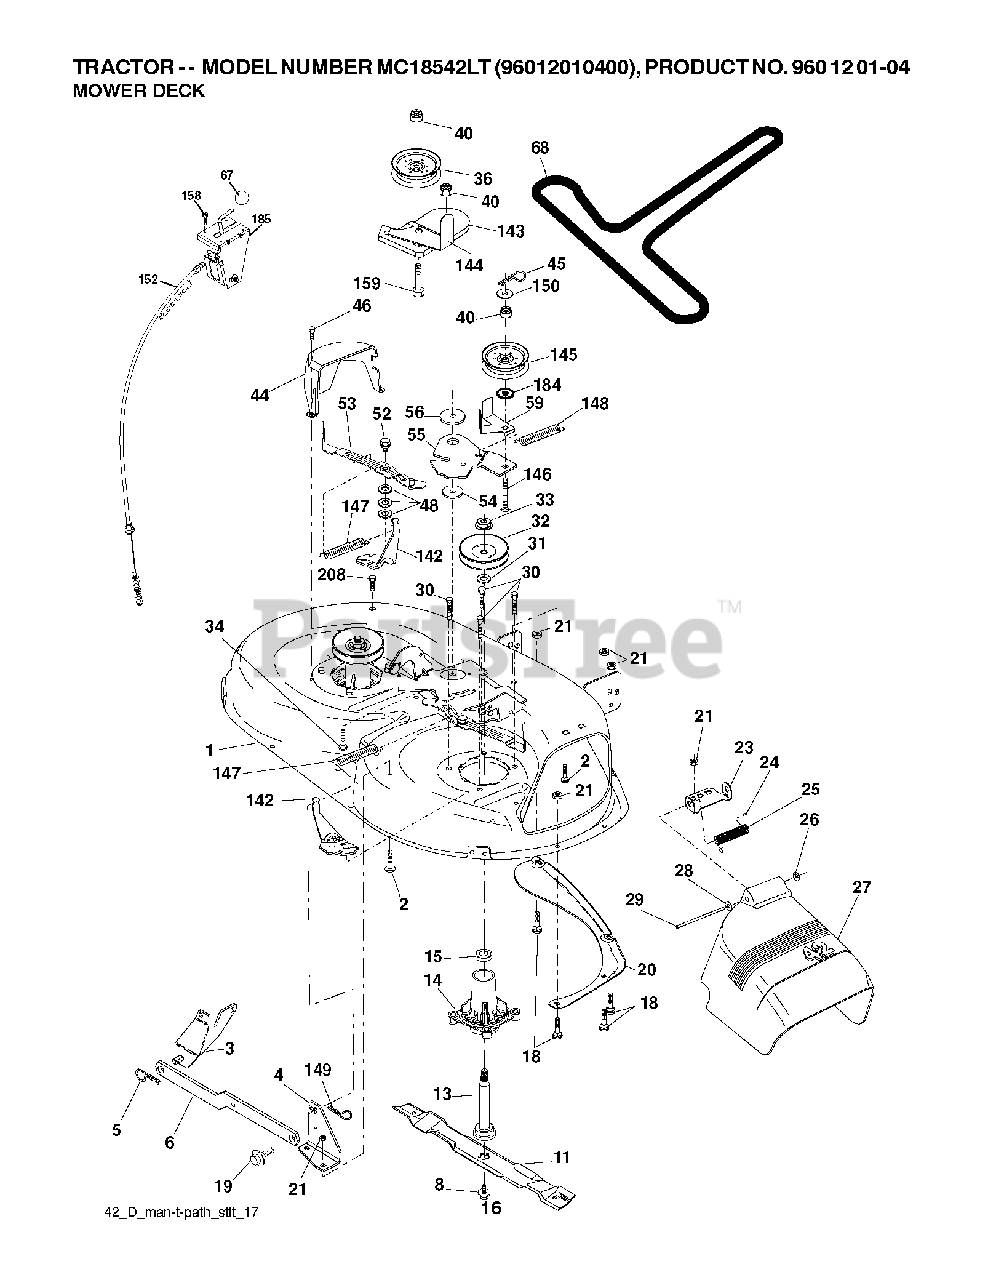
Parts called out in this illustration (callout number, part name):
2	BOLT
3	BRKT ASM SWAY BAR
4	BRACKET SWAY BAR 42" DECK
5	RETAINER-SPRNG RB
6	BAR SWAY DECK
8	BOLT.WASHER.ASM.7/16-2
11	42" HI-LIFT BLADE
13	SHAFT.ASM.MDRL.N/GREASE.38
14	HOUSING.MANDREL.4PT.
18	BOLT
19	BOLT SHD 5/16-18
20	BAFFLE.VORTEX
21	LOCKNUT
23	BRKT, DEFL. MOWER
24	CAP-SLEEVE LT
25	SPRING TORSION
26	NUT PUSH M
27	SHIELD DEFLECTOR
28	WASHER
29	ROD.HINGE
30	SCREW, WASHER HEAD
31	WASHER.SPACER.MANDREL
32	PULLEY/MANDREL
33	NUT.FLANGE.LOCK.TOP
34	BOLT.3/8-16X1.50
36	FLAT IDLER PULLEY
40	NUT LOCK FLG 3/8-16 UNC
44	GUARD MANDREL LH BLACK
46	SCREW.1/4-20X5/8
52	BOLT.SHOULDER.5/16-18
53	ARM BRAKE ASSY
55	ARM IDLER 42" MOWER LT/YT
56	SPACER.RETAINER.MOWER
59	GUARD, BELT
67	KNOB T (3/8 HOLE)
68	BELT V SECONDARY
142	ANCHOR SPRING BRAKE MOWER
143	BRACKET, ARM IDLER
144	KEEPER.BELT.42".CLUTCH.CABLE
145	PULLEY
146	BOLT, CARRIAGE IDLER BLACK
147	SPRING EXTENSION
148	IDLER RETURN SPRING
149	SPRING.RETAINER.YELLOW.ZINC
150	WASHER LT
152	Clutch Cable Kit
158	SCREW
159	BOLT
184	WASHER
185	HEAD ASM. CABLE CLUTCH
208	SCREW 3/8-16X1/2
